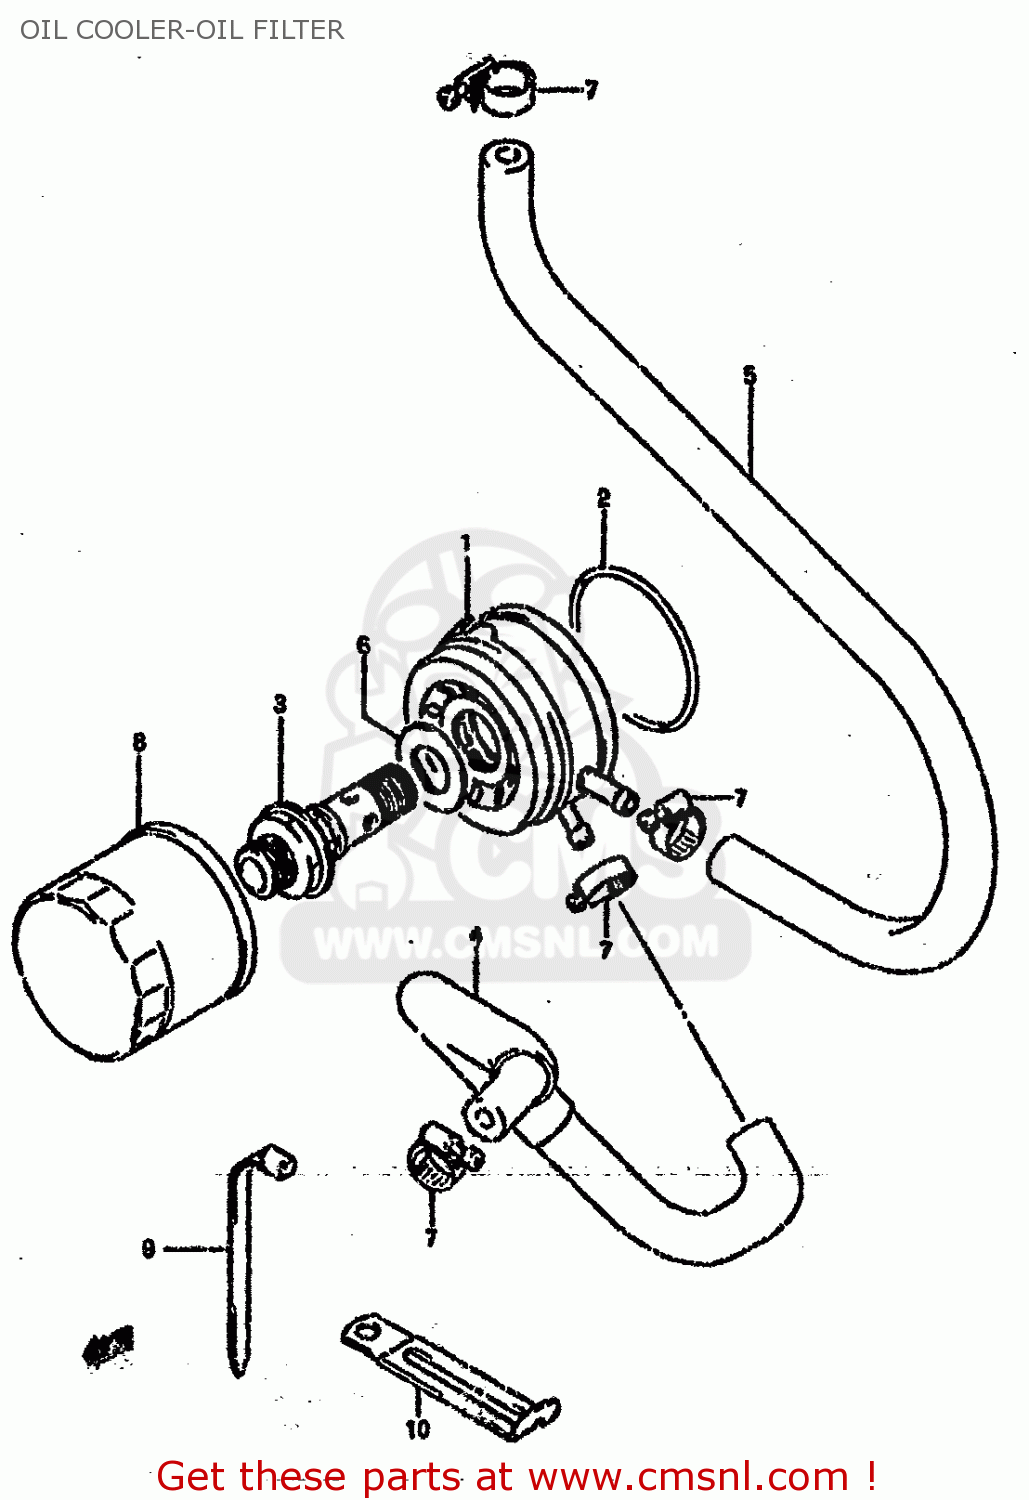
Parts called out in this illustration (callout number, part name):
1	COOLER ASSY,OIL
2	O RING(D:3.1,ID:63.9)
3	BOLT,OIL COOLER UNION
4	HOSE,OIL COOLER WATER IN
5	HOSE,OIL COOLER OUTLET
6	SHIM
7	CLIP
8	FILTER ASSEMBLY,ENGINE OIL
9	CLAMP L:165
10	CLAMP
